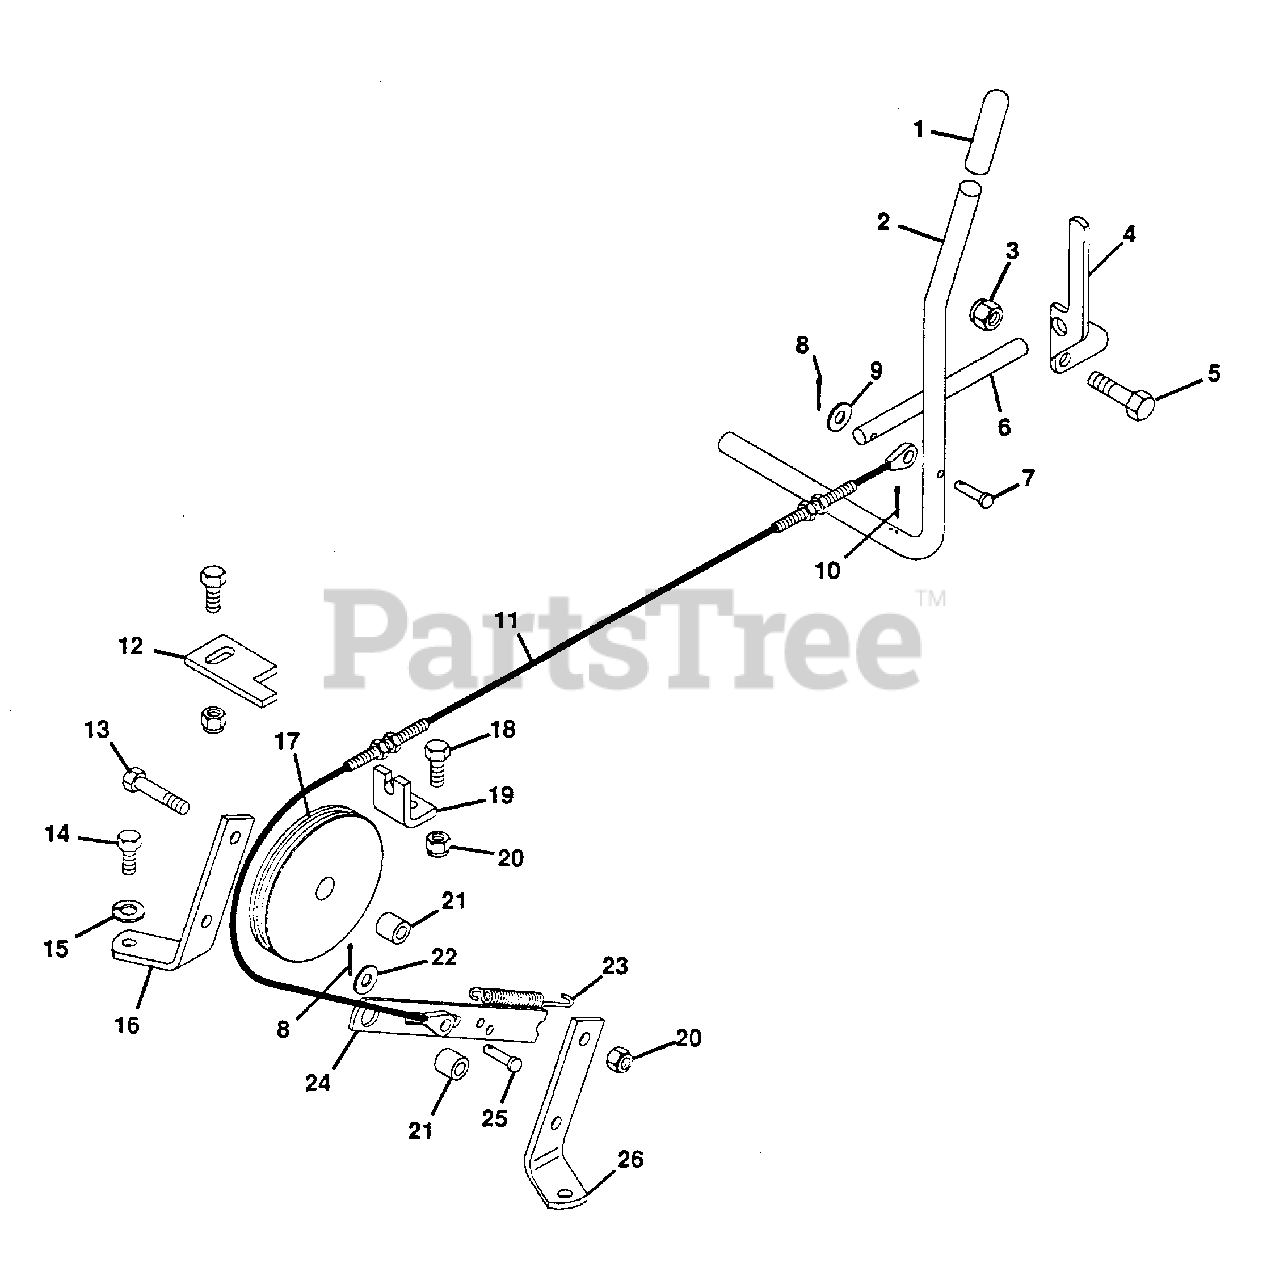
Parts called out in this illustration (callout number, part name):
1	GRIP, HANDLE
2	LEVER, BRAKE
3	NUT, LOCK 3/8-16
4	ARM, PARKING BRAKE LOCK
5	BOLT, HEX 3/8-16X1.00
6	ROD, BRAKE LOCK
7	PIN, CLEVIS
8	PIN, COTTER .06X.75
9	WASHER, FLAT .312X.734X.065
10	PIN, COTTER .094X1.25
11	CABLE, EMERGENCY BRAKE
12	KEEPER
13	BOLT, HEX 5/16-18X1.375
14	BOLT, HEX 5/16-18X.75
15	WASHER, LOCK 5/16 REG.
16	BRACKET, BRAKE PULLEY R.H.
17	PULLEY, CABLE
18	BOLT, HEX 5/16-18X.875
19	BRACKET, CABLE
20	NUT, LOCK 5/16-18
21	SPACER, .328X.50X.54
22	WASHER, FLAT .281X.625X.065
23	SPRING, EXTENSION
24	BAR, BRAKE
25	PIN, CLEVIS
26	BRACKET, BRAKE PULLEY L.H.
